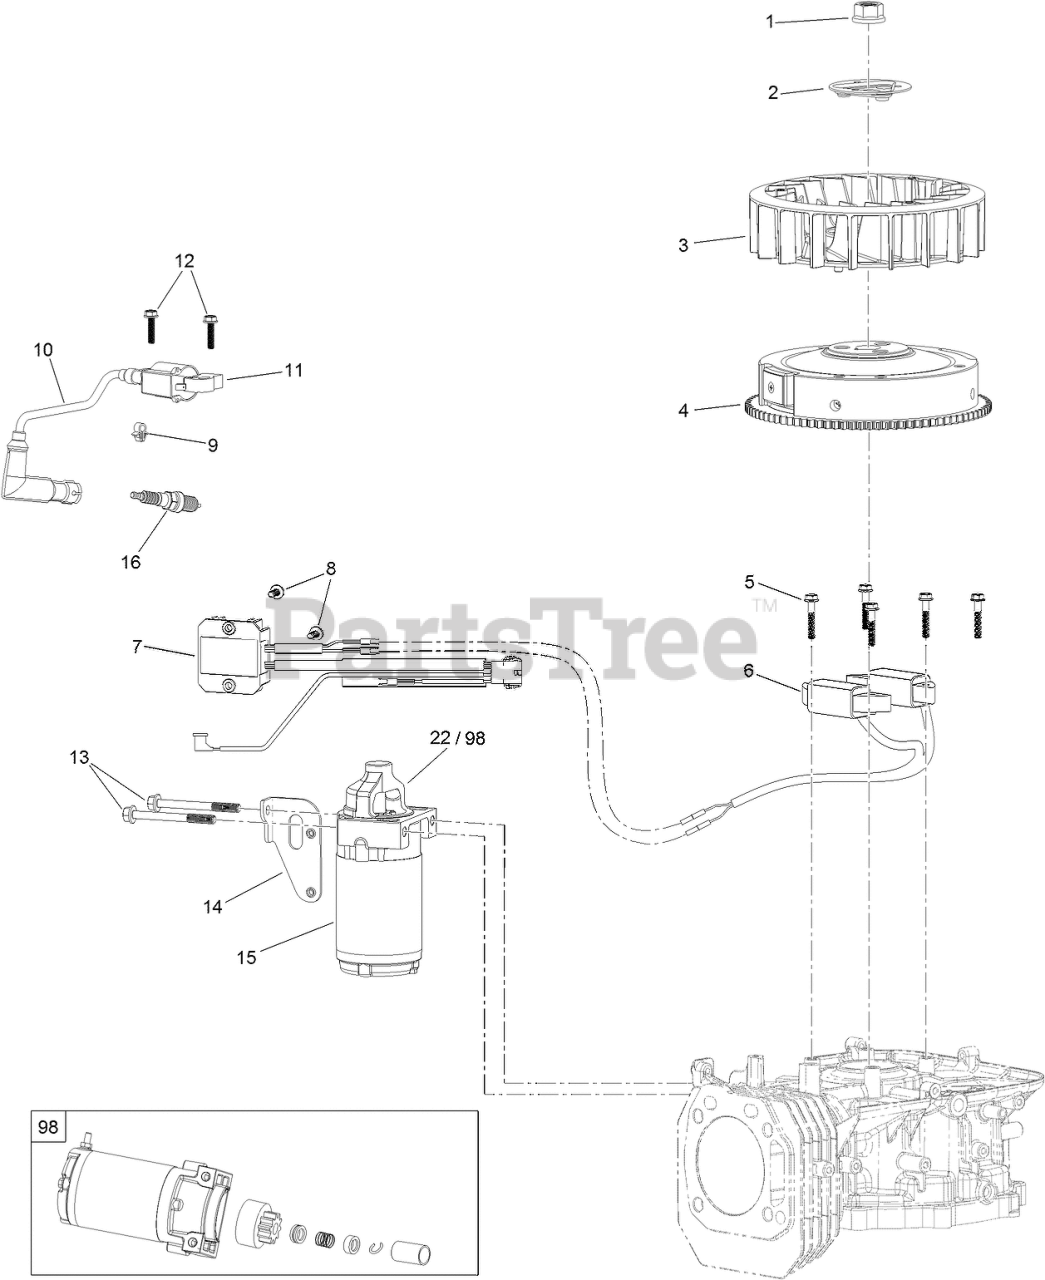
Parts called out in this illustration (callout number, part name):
1	NUT-FLANGE
2	PULLEY-STARTER
3	FAN-COOLING
4	FLYWHEEL
5	SCREW-HHF
6	ALTERNATOR
7	VOLTAGE REGULATOR
8	SCREW-HHF
9	CLAMP-WIRE
10	BOOT-PLUG, SPARK
11	IGNITION COIL ASM
12	SCREW-HHF
13	SCREW-HHF
14	BRACKET-STARTER
15	STARTER-ELECTRIC
16	PLUG-SPARK
22	PINION
98	STARTER REPAIR KIT
